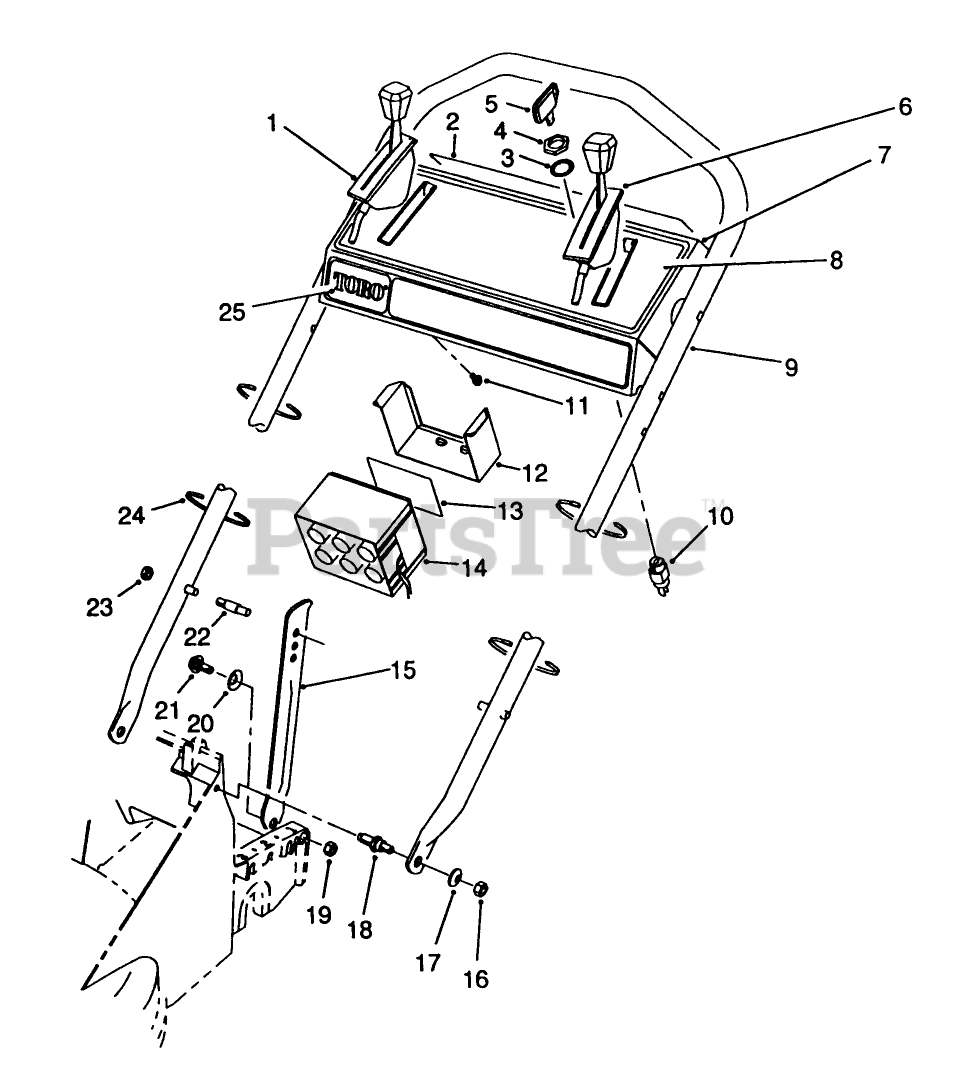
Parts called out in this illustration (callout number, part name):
3	KEY-IGNITION
4	NUT-HH
5	WASHER-LOCK
10	STARTER SWITCH ASM
11	SCREW-HWHTF
14	BATTERY ASSEMBLY,WET
16	NUT-LOCK
17	WASHER-PLAIN
18	CLAMP
19	NUT-LOCK, NI
20	WASHER-BELLEVILLE
22	HANDLE PIN
23	NUT-LOCK, NI
24	TIE-CABLE
